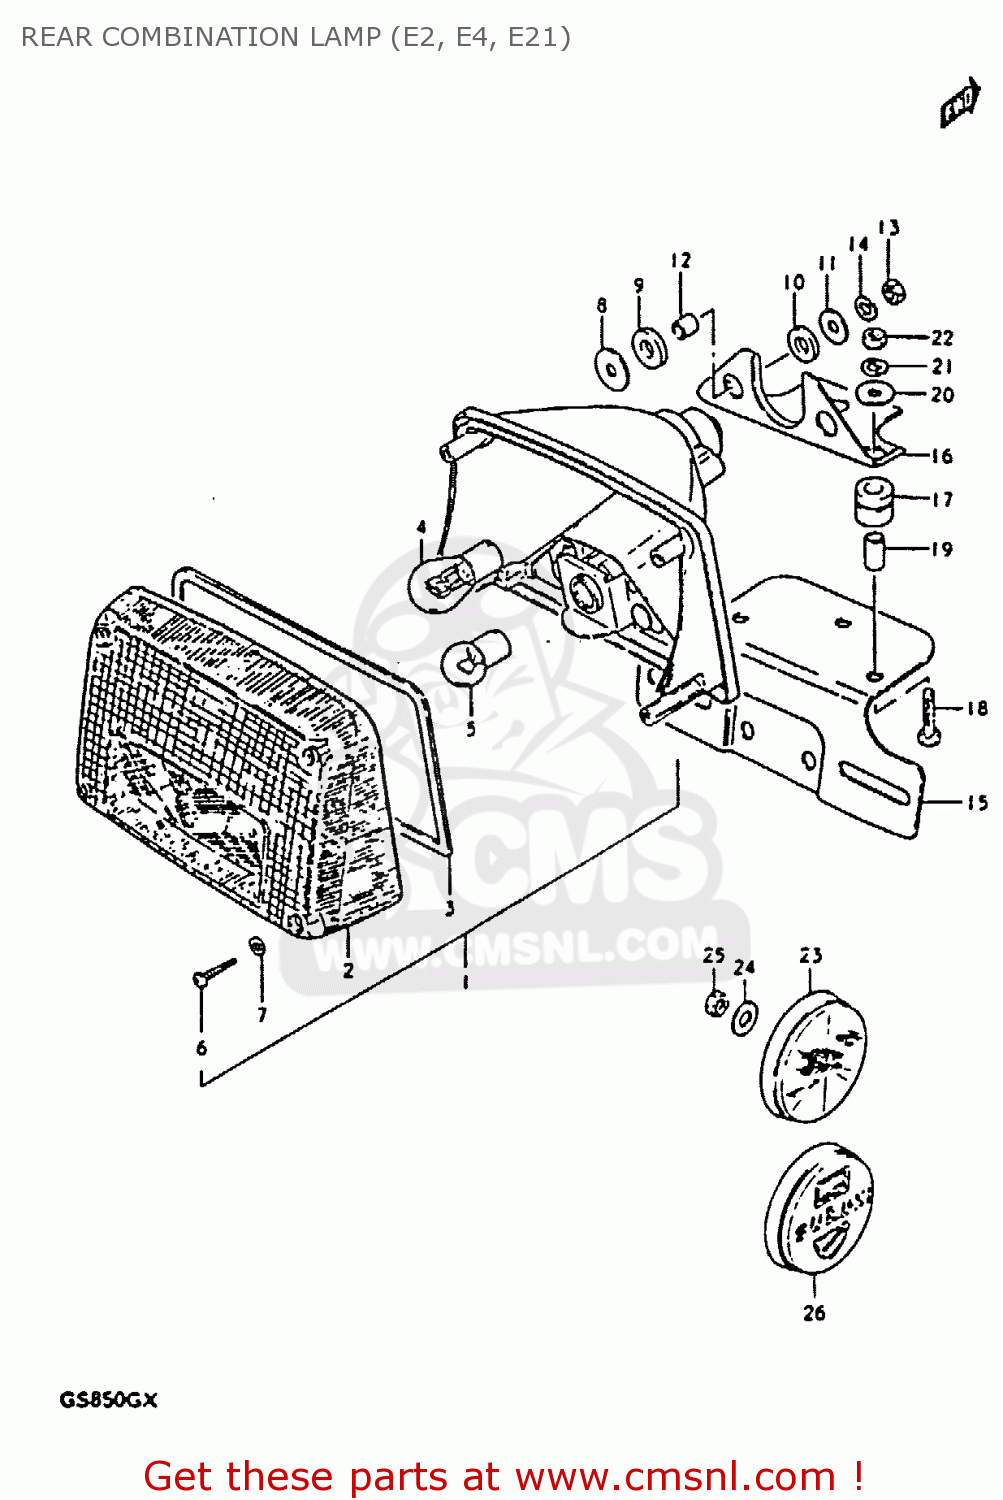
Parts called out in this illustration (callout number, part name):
1	LAMP, REAR COMBINATION
2	LENS
3	GASKET (NAS)
4	BULB 12V21/5W
5	BULB
6	SCREW,REAR COMBINATION LAMP
7	GASKET (NAS)
8	WASHER
9	CUSHION
10	CUSHION
11	WASHER(6,5X22X1.6)
12	SPACER(6.1X9X7.5)
13	NUT
14	LOCK WASHER
15	BRACKET, LICENCE PLATE
16	BRACKET,LICENSE PLATE
17	CUSHION, BRACKET
18	BOLT
19	SPACER (6.4X9X15.5)
20	WASHER
21	LOCK WASHER
22	NUT
23	REFLEX REFLECTOR,RR
24	WASHER
25	NUT
26	EMBLEM, REAR SIDE
